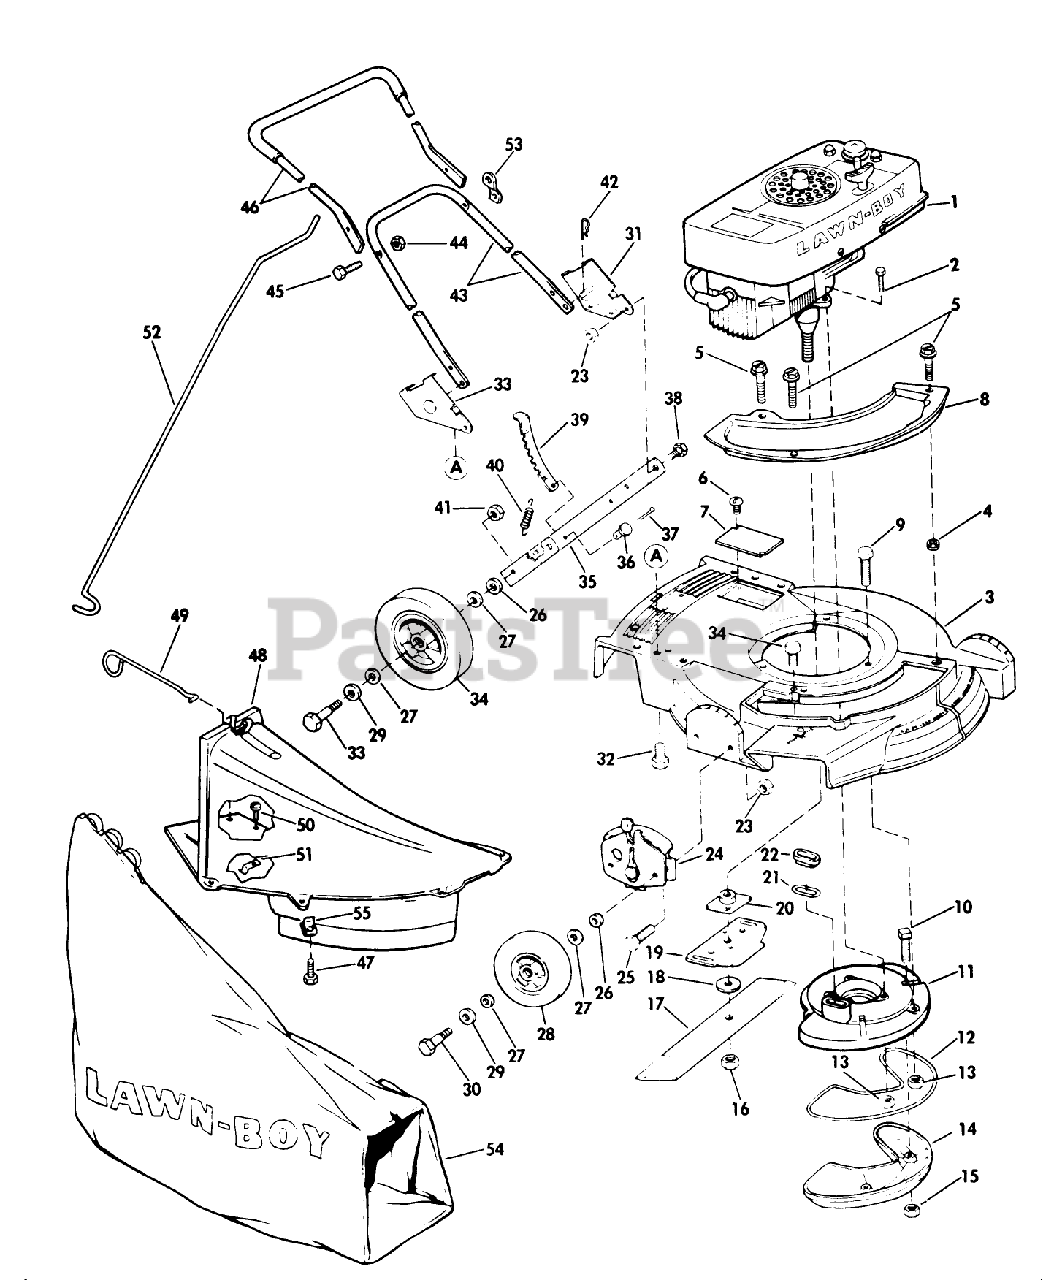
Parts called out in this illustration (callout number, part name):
5	SCREW SEMS TRM HEX HD
8	Cover-Chute (19" 21" Models)
9	SCREW
13	NUT
15	LOCKNUT E
16	NUT-BLADE
18	WASHER
20	PLATE AND COLLAR ASM
21	GASKET S
22	SLEEVE
23	NUT
26	WASHER WROUGHT
27	WASHER
28	WHEEL & TIRE KIT
29	SPACER
30	BOLT WHEEL
32	SCREW
33	BOLT
38	BOLT-SHOULDER
40	SPRING N.A.S
41	LOCKNUT
42	HAIR PIN
44	Nut-Handle
45	SCREW
47	SCREW
48	Chute Skirt
52	ROD & CLIP
55	SPEED NUT ARDEN
